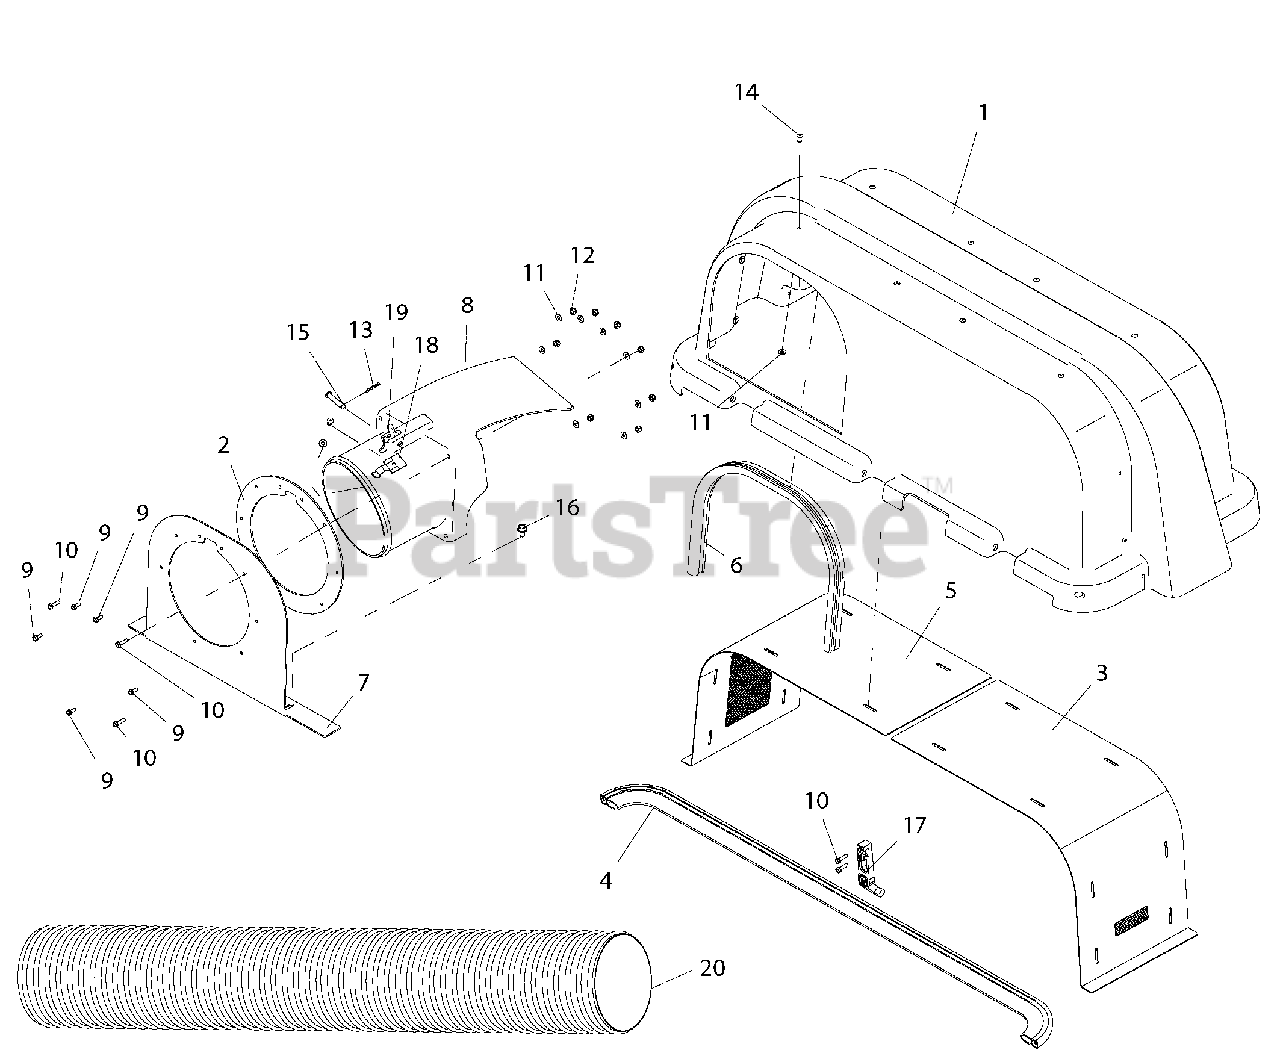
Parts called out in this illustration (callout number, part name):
1	COVER, 2-BUCKET BAGGER
2	SEAL, UPPER BOOT
3	WMT-BAGGER HOOD VENT, LH
4	SEAL, BULB - BAGGER HOOD
5	WMT-BAGGER HOOD VENT, RH
6	SEAL, BULK
7	WLDMT, TUBE SUPPORT
8	BOOT, UPPER
9	@SCR-MCH 10-24X.50 HWH YWZC
10	@SCR-MCH 10-24X.75 HWH YWZC
11	@WSHR-FL-STL.219X.50X.049 YWZC
12	@NUT-LK-NYL 10-24 W/INSRT YWZC
13	PIN-HAIR, ENDRIES #25 YWZC
14	.187X.6835 DOME ST
15	PIN-CLEV .309 X 1.625 YWZC
16	@SCR-TAP .31-18X.50 HWH TR YWZ
17	LATCH, RUBBER
18	THUMB LATCH
19	INDICATOR, FLOW
20	BAGGER, HOSE 51"
20	HOSE, FLEXIBLE-47"
